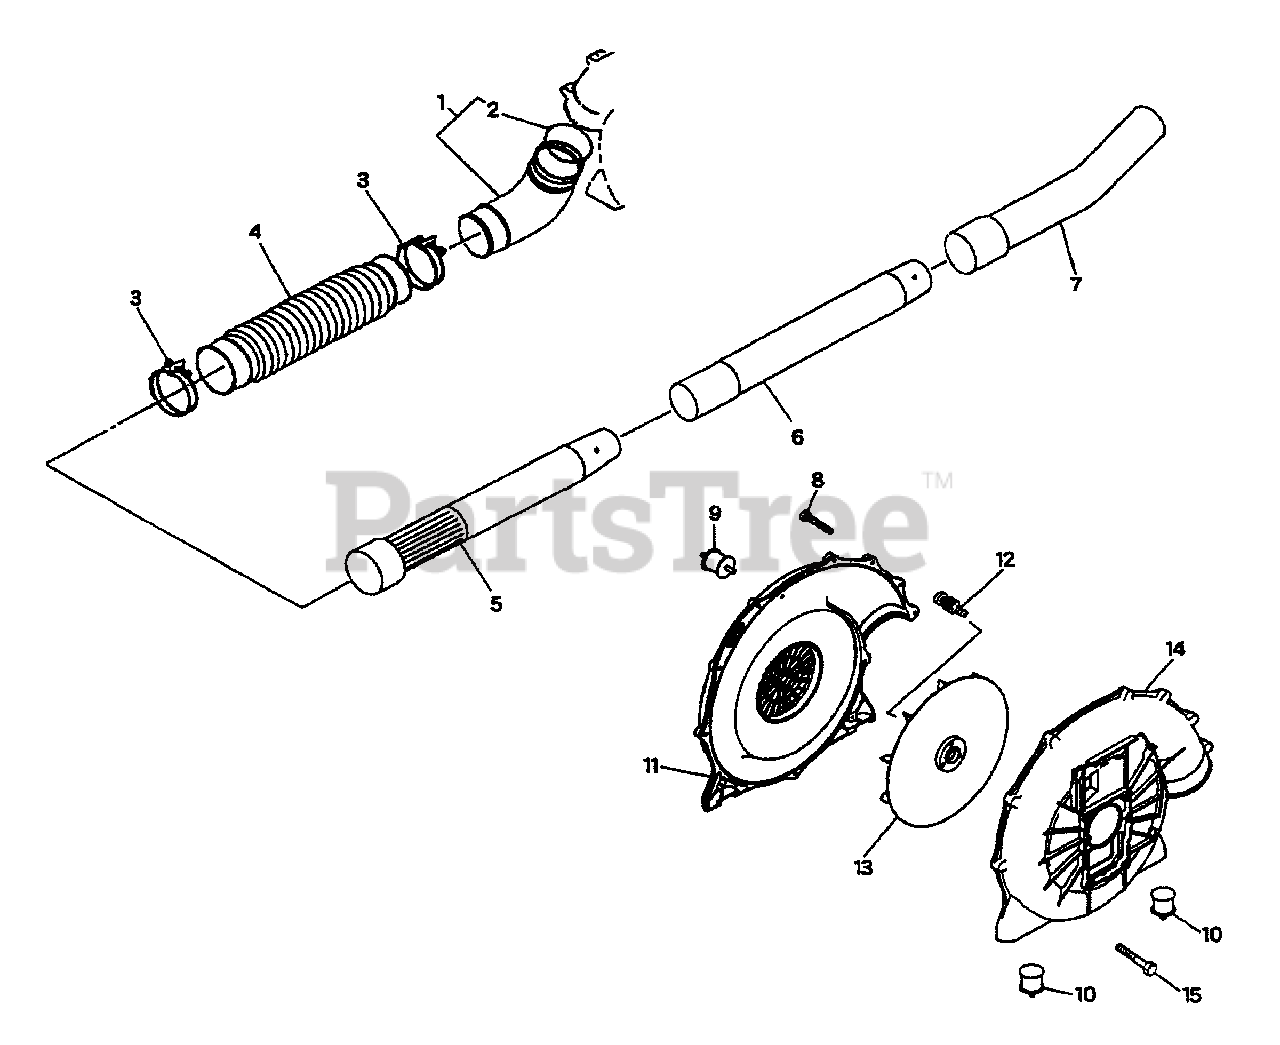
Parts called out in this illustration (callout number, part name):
1	Elbow Pipe Compl.
2	O-Ring
3	Clamp
4	Flexible Pipe
5	Base Pipe
6	Middle Pipe
7	Bend Pipe
8	Tapping Screw (M5x20)
9	Rubber AV Mount
10	Rubber AV Mount
11	Fan Housing
12	Pre-Coat Lock Bolt
14	Fan Housing
15	Pre-Coat Lock Bolt
